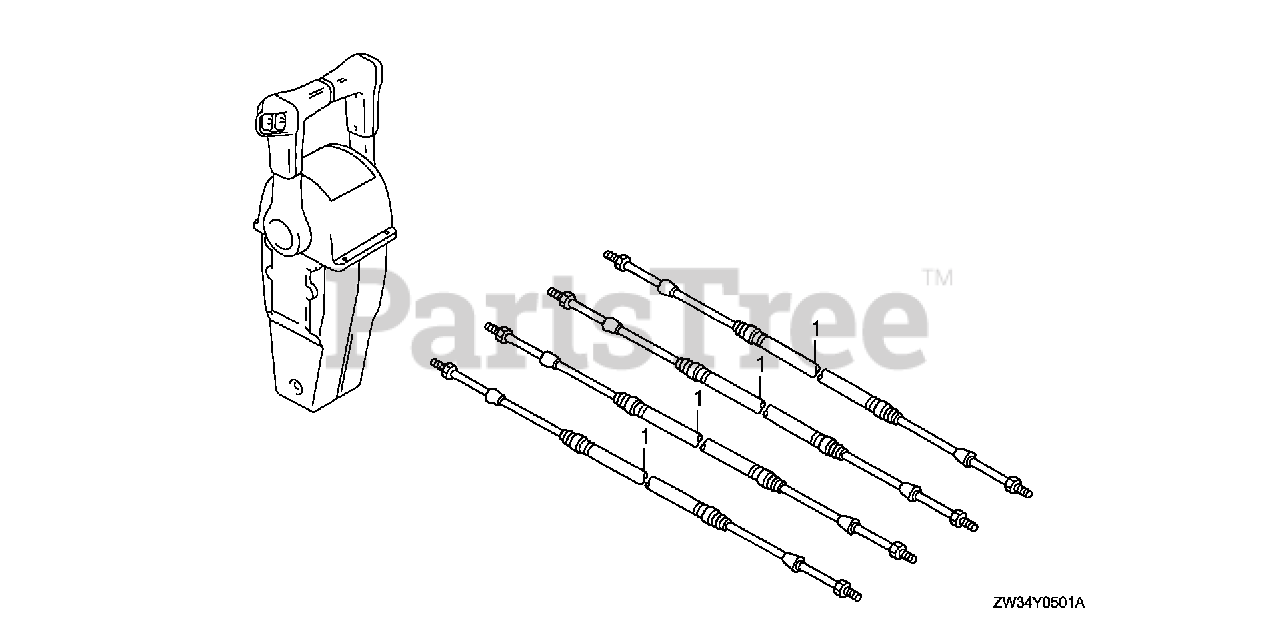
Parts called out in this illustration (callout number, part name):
1	CABLE, REMOTE CONTROL (10'') (LOW FRICTION)
1	CABLE ASSY., PUSH-PULL (33C-5FT)
1	CABLE, REMOTE CONTROL (11'') (LOW FRICTION)
1	CABLE ASSY., PUSH-PULL (33C-6FT)
1	CABLE, REMOTE CONTROL (12'') (LOW FRICTION)
1	CABLE ASSY., PUSH-PULL (33C-7FT)
1	CABLE, REMOTE CONTROL (13'') (LOW FRICTION)
1	CABLE ASSY., PUSH-PULL (33C-8FT)
1	CABLE, REMOTE CONTROL (14'') (LOW FRICTION)
1	CABLE ASSY., PUSH-PULL (33C-9F T)
1	CABLE, REMOTE CONTROL (15'') (LOW FRICTION)
1	CABLE ASSY., PUSH-PULL (33C-10FT)
1	CABLE, REMOTE CONTROL (16'') (LOW FRICTION) (NOT AVAILABLE)
1	CABLE ASSY., PUSH-PULL (33C-11FT)
1	CABLE, REMOTE CONTROL (17'') (LOW FRICTION)
1	CABLE ASSY., PUSH-PULL (33C-12 FT)
1	CABLE, REMOTE CONTROL (18') (LOW FRICTION) (NOT AVAILABLE)
1	CABLE ASSY., PUSH-PULL (33C-13 FT)
1	CABLE, REMOTE CONTROL (1 9'') (LOW FRICTION)
1	CABLE ASSY., PUSH-PULL (33C-14FT)
1	CABLE, REMOTE CONTROL (20'') (LOW FRICTION) (NOT AVAILABLE)
1	CABLE ASSY., PUSH-PULL (33C-15 FT)
1	CABLE, REMOTE CONTROL (21') (LOW FRICTION)
1	CABLE ASSY., PUSH-PULL (33C-16FT)
1	CABLE, REMOTE CONTROL (22') (LOW FRICTION) (NOT AVAILABLE)
1	CABLE ASSY., PUSH-PULL (33C-17 FT)
1	CABLE, REMOTE CONTROL (2 3'') (LOW FRICTION)
1	CABLE ASSY., PUSH-PULL (33C-18 FT)
1	CABLE, REMOTE CONTROL (24') (LOW FRICTION) (NOT AVAILABLE)
1	CABLE ASSY., PUSH-PULL (33C-19FT)
1	CABLE, REMOTE CONTROL (25') (LOW FRICTION)
1	CABLE ASSY., PUSH-PULL (33C-20FT)
1	CABLE, REMOTE CONTROL (26') (LOW FRICTION)
1	CABLE ASSY., PUSH-PULL (33C-21FT)
1	CABLE, REMOTE CONTROL (27') (LOW FRICTION)
1	CABLE ASSY., PUSH-PULL (33C-22FT)
1	CABLE, REMOTE CONTROL (28') (LOW FRICTION) (NOT AVAILABLE)
1	CABLE ASSY., PUSH-PULL (33C-23FT)
1	CABLE, REMOTE CONTROL (2 9') (LOW FRICTION)
1	CABLE ASSY., PUSH-PULL (33C-24FT)
1	CABLE, REMOTE CONTROL (30') (LOW FRICTION) (NOT AVAILABLE)
1	CABLE ASSY., PUSH-PULL (33C-25FT)
1	CABLE, REMOTE CONTROL (31') (LOW FRICTION)
1	CABLE ASSY., PUSH-PULL (33C-26FT)
1	CABLE, REMOTE CONTROL (32') (LOW FRICTION) (NOT AVAILABLE)
1	CABLE ASSY., PUSH-PULL (33C-27FT)
1	CABLE, REMOTE CONTROL (33') (LOW FRICTION)
1	CABLE ASSY., PUSH-PULL (33C-28FT)
1	CABLE, REMOTE CONTROL (34') (LOW FRICTION)
1	CABLE ASSY., PUSH-PULL (33C-29FT)
1	CABLE, REMOTE CONTROL (35') (LOW FRICTION)
1	CABLE ASSY., PUSH-PULL (33C-30FT)
1	CABLE ASSY., PUSH-PULL (33C-31FT)
1	CABLE ASSY., PUSH-PULL (33C-32FT)
